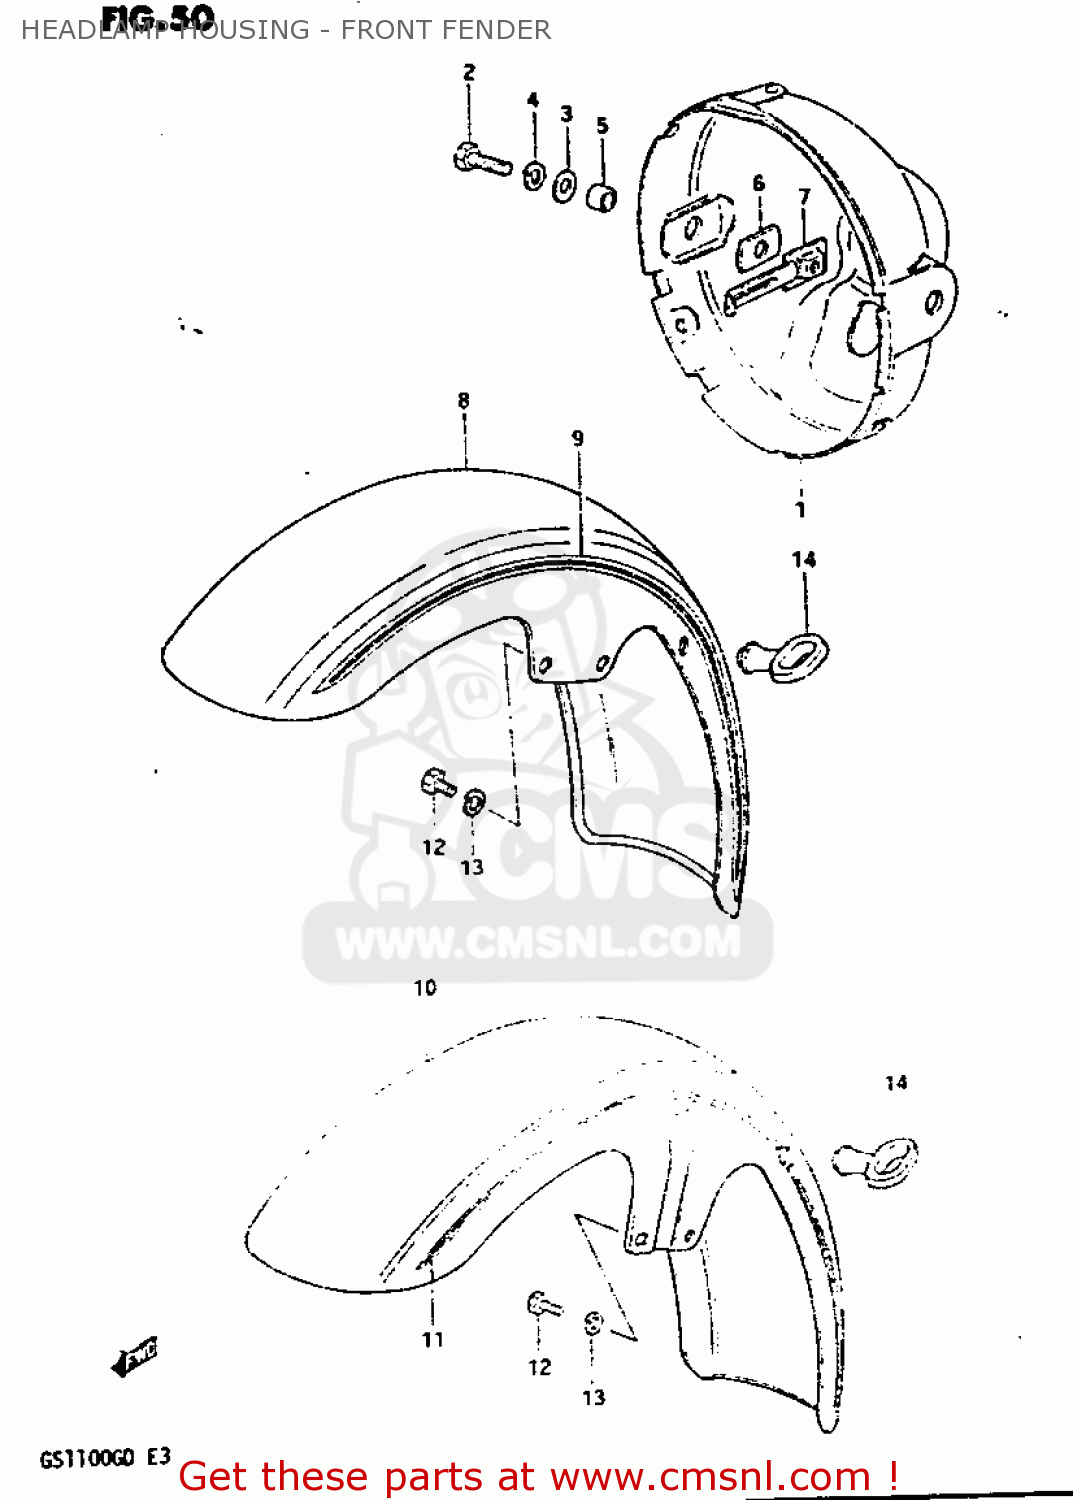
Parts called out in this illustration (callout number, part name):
1	HOUSING,HEADLAMP
2	BOLT
3	WASHER
4	LOCK WASHER
5	SPACER (8.8X12X7)
6	CUSHION
7	PLATE,HEADLAMP HOUSING
8	FENDER,FRONT
9	TAPE,FRONT FENDER
10	FENDER,FRONT
11	TAPE,FRONT FENDER
12	BOLT
13	LOCK WASHER
14	GUIDE,CABLE
